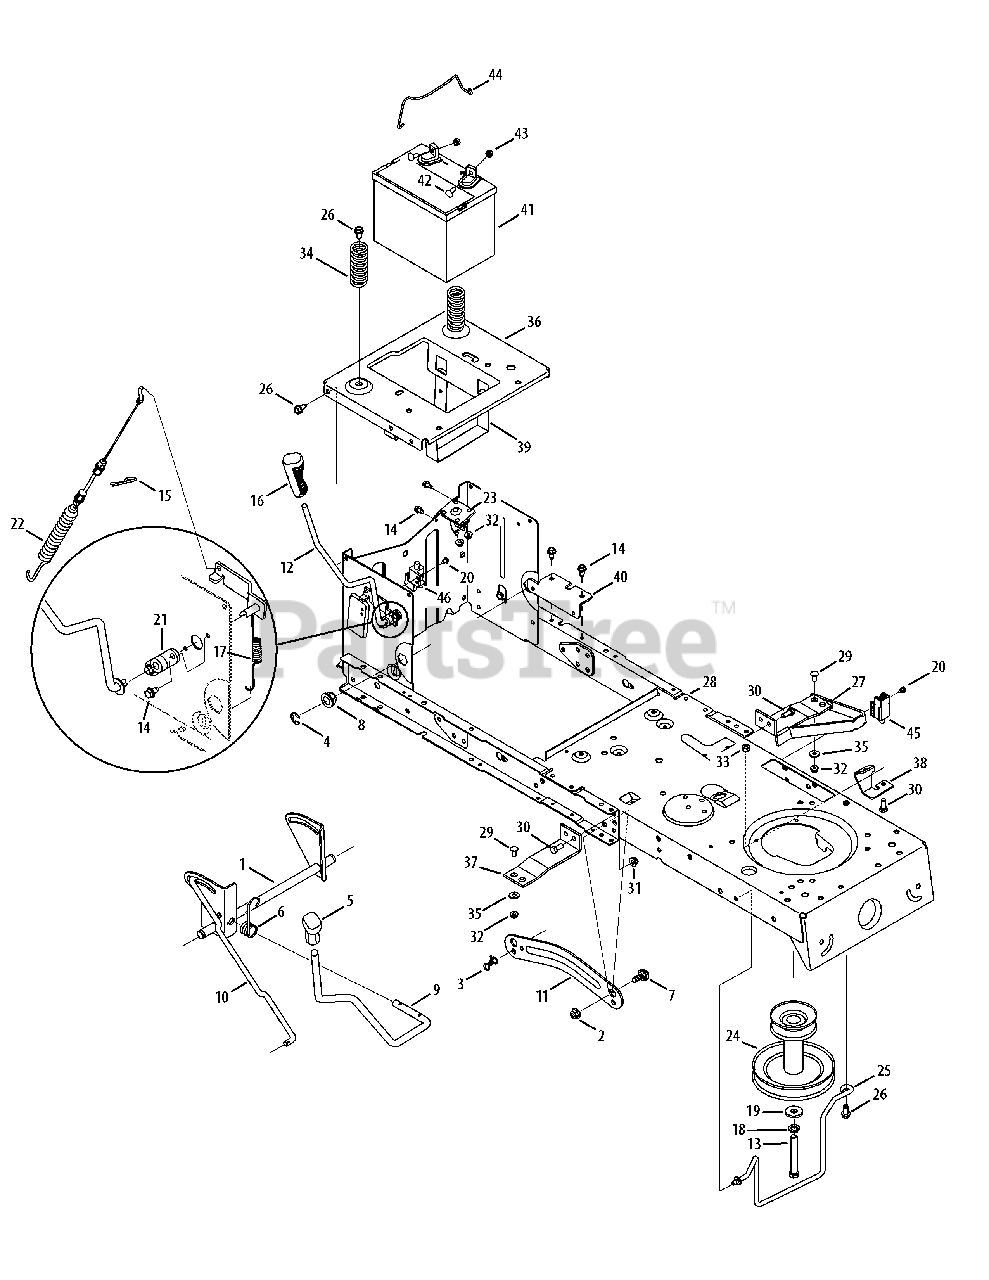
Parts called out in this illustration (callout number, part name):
1	Shaft, Lift
2	Nut, Hex Flange Insert Lock, 3/8-16
3	Bow-Tie Pin, 91, RH
4	E-ring, .625 Shaft
5	Grip, Handle
6	Spring, Lift Handle Torsion
7	Bolt, Shoulder, .625 x .175:3/8-16
8	Bearing, Hex Flange,
9	Handle, Lift
10	Lift Rod, 13.68
11	Arm, Deck Lift RH
11	Arm, Deck Lift LH
12	PTO Handle Assembly
13	Screw, Hx. Hd., 7/16-20 x 3.25
14	Screw, Hd. Tapp, 1/4-20 x .5
15	Click Pin
16	Handle Grip
17	PTO Spring, Extension
18	Washer, Flat, 7/16
19	Washer, Flat, .450 x .250 x .164
20	Shoulder Screw, #10-32 x .500
21	PTO Bearing
22	Deck Engagement Cable
23	12v. Solenoid
24	Engagement Pulley
25	Belt Keeper Rod Assembly
26	Screw, Hd. Tapp, 5/16-18 x .75
27	Support Bracket Assembly
28	Rider Frame Assembly
29	Carriage Screw, 1/4-20 x .62
30	Screw, Hx. Hd., 5/16-18 x .75
31	Nut, Hex Flange Insert Lock, 5/16-18
32	Nut, Hex Flange Insert Lock, 1/4-20
33	Hexlock Nut, 5/16-18
34	Spring, Compress., 1.28 x 3.125
35	Flat Washer, .28 x .74 x .063
36	Seat Bracket Frame
37	Running Board Bracket
38	Frame Support Bracket
39	Battery Bracket
40	Frame Brace Bracket
41	Die Hard Battery
42	Screw, Shoulder, .250 x .150
43	Nut, Sems, 1/4-20
44	Battery Rod
45	Screw Mount Interlock Switch
46	Interlock Switch
